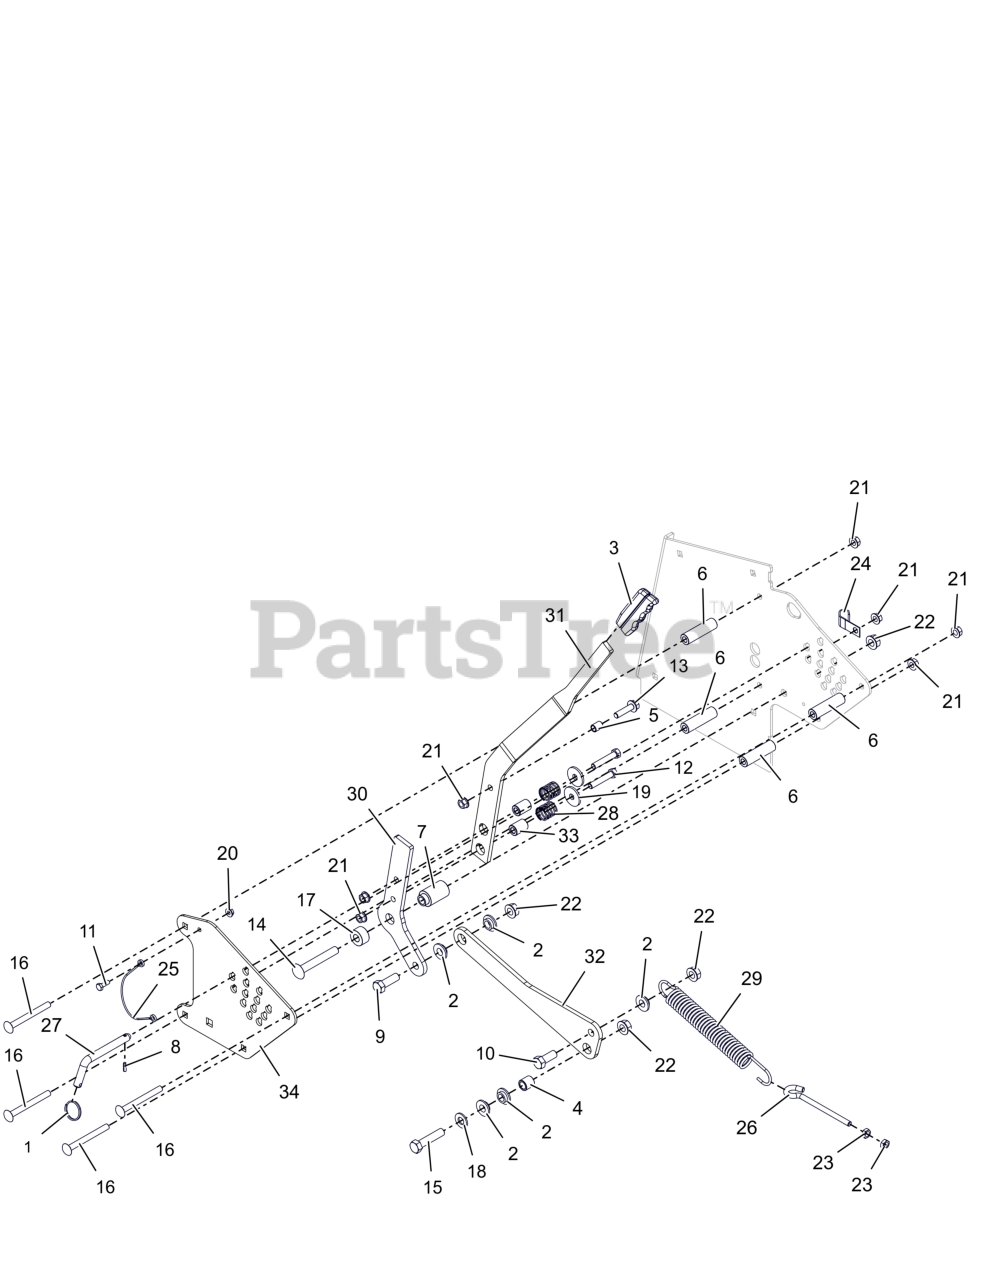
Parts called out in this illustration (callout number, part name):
1	RING, WIRE - .080 X 1.25
2	BSHG-FLG .515X.750X.395X1.120
3	GRIP, PARKING BRAKE (GREY)
4	BSHG-SLV .510X.751X.750
5	SPCR, SLV .385X.500X.652
6	SPCR, .390" ID .750 OD X 2.646
7	BSHG, SLV 1.125 X 0.515 X 2.013
8	PIN-ROLL .188X.63
9	BLT,HEX .50-13X1.50 G5 ZCC
10	BLT,HEX .50-13X1.25 G5 ZCC
11	BLT, HEX .25-20X.75 G5 ZCC
12	BLT,HEX .38-16X2.00 G5 ZCC
13	BLT,HEX-FLG .38-16X1.50 G5 ZCC
14	BLT, RHSSN .50-13X3.50 G5 ZCC
15	BLT, HEX .50-13X2.25 G5 ZCC
16	BLT,RHSSN .375-16 X 3.75 G5 ZCC
17	SPCR SLV .515 X 1.125 X .634
18	WSHR,FLT .531X1.062X.095 ZCC
19	WSHR,FLT .406X1.375X.135 ZCC
20	NUT-LK-CTR-FLG .25-20 ZC120
21	NUT-LK-CTR-FLG .375-16 GF ZCC
22	NUT-LK-CTR-FLG .500-13 GG ZCC
23	NUT-JAM .375-16 G2 ZCC
24	J-CLAMP
25	CABLE, 12.0 LANYARD, NYLON
26	BOLT,.38-16 X 4.25-.62 DIA EYE
27	PIN, HOC SELECTOR/PLTFRM LOCK
28	SPRG, COMPRESSION
29	SG-TENS .162X1.25X8.25 WLD 25
30	PLATE, HANDLE BASE (BLACK)
31	HANDLE, DECK LIFT UPPER (BLACK)
32	PLATE, DECK HEIGHT MECHANISM (BLACK)
33	SPCR, .750 OD X .390 ID X 1.063
34	PLATE, HOC PIN LOCATOR (ORANGE)
